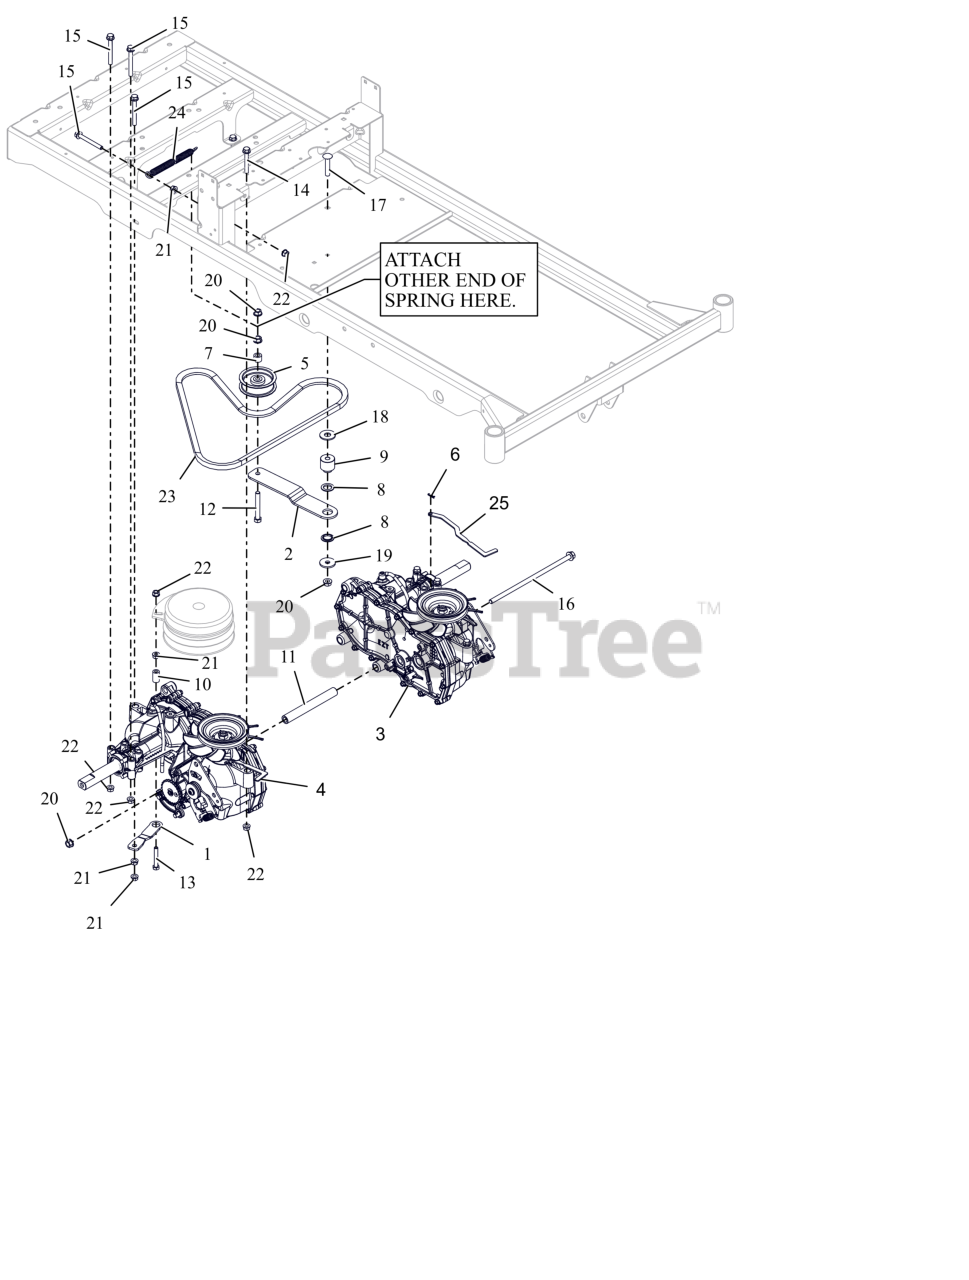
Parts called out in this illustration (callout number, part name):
1	BRKT, CLUTCH
2	IDLER ARM, GROUND DRIVE
3	TRANSAXLE EZT D-SHFT SHORT
4	TRANSAXLE EZT D-SHFT SHORT
5	PULLEY, ENGINE CLUTCH 03608
6	PIN, HAIR #178 .06X.77 ZCC
7	BSHG-SLV .407X.625X.750 PL
8	BUSHING, IDLER ARM
9	SPACER, GROUND DRIVE IDLER
10	SPACER, RUBBER 5/16 IDX1.0 LG
11	SPCR, TRANSAXLE .438 ID X .750 OD X 8.18
12	BLT, HEX .38-16X2.75 G5 ZCC
13	BLT, HEX .31-18X2.00 G5 ZCC
14	BLT,HEX-FLG .31-18X2.25 G5 ZCC
15	BLT,HEX-FLG .31-18X2.75 G5 ZCC
16	BLT, HEX-FLG 0.375-16X9.75 GR5 ZC120
17	BLT,RHSSN.375-16X2.00 G5 ZCC
18	WSHR,FLT .563X1.375X.109 ZCC
19	WSHR,FLT .406X1.375X.135 ZCC
20	NUT-LK-CTR-FLG .375-16 GF ZCC
21	NUT,SPNLK-FLG .31-18 G5 ZCC
22	NUT,LK-CTR-FLG .31-18 GF ZCC
23	V-BELT, HA-RAW EDGE
24	SPRING, EXTENSION
25	BRKT, VALVE DUMP (BLACK)
